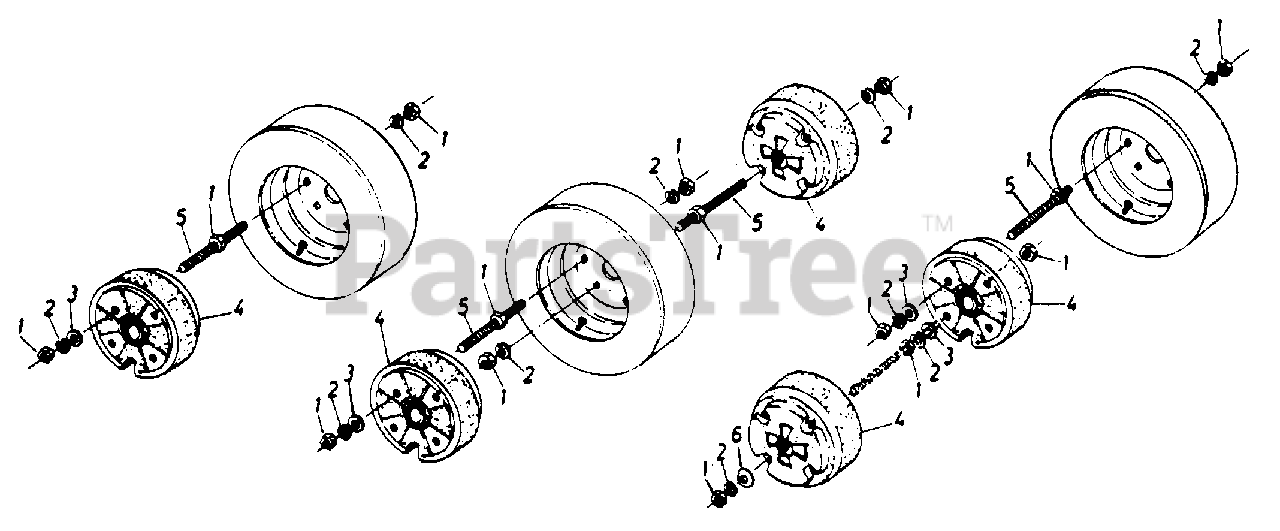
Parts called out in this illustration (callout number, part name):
1	Hex Nut 1/2-13 Thd.
2	Lock Washer 1/2 I D
3	FlatWasher 53' I D x 93' 0 D
4	Wheel Weight
5	4 Rod Threaded 1/2-13 x 9 50 Lg.
6	4 Fl -Washer 50' I D x 2 00' O D.
